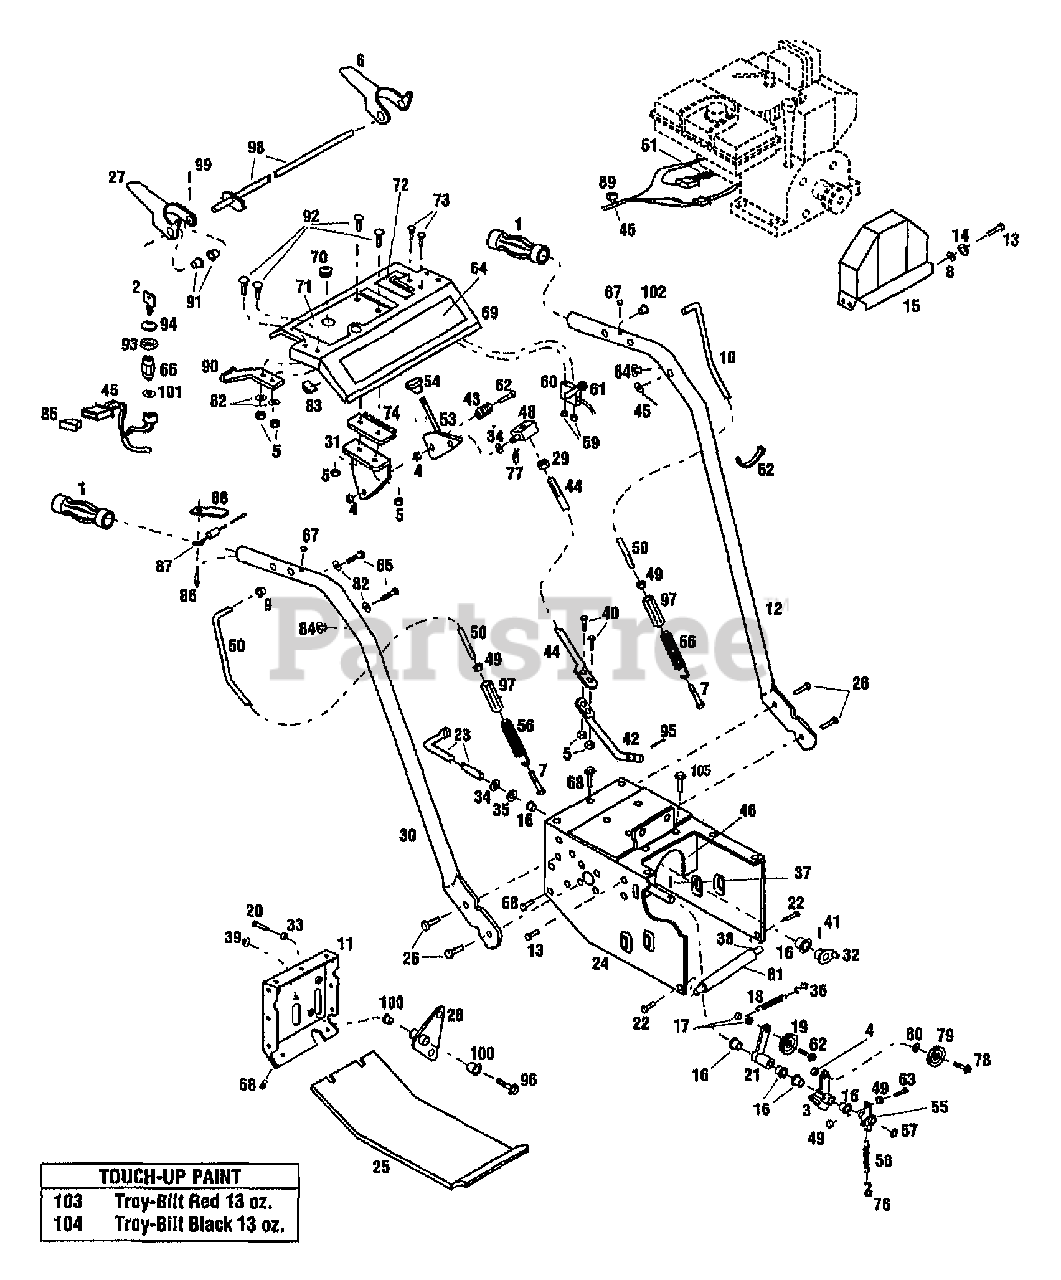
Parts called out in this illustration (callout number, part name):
1	GRIP-HANDLE
2	KEY-IGNITION
3	ARM-IDLER
4	NUT-LOCK 3/8-16
5	NUT-HT LK 1/4-20
6	HANDLE-CONTROL LH
7	SCR-PH 5/16-18X1.0
8	WASHER-FLAT 5/16 SAE
8	WASHER-LK .312 ZP
9	NUT-PUSH
10	ROD-CLUTCH WHEEL DRIVE
11	PLATE-BACK
12	HANDLEBAR-LH
13	SCR-HHC 5/16-18X.75 GR 5 ZP
14	WASHER-FLAT 5/16 SAE
15	COVER-BELT
16	BUSHING-.5X.21 NYLON FLNG
17	NUT-HEX/JAM 3/8-16 ZP
18	SPRING-EXTENSION
19	PULLEY-IDLER
20	SCR-HFLK 5/16-18X1.75 ZP G5
21	ARM-IDLER
22	SCR-HFLK 5/16-18X.75 ZP
23	ARM-CONTROL
24	ASSM-FRAME
25	COVER-BOTTOM
27	HANDLE-CONTROL RH
28	ARM-CONTROL SPEED
29	NUT-HEX 3/8-16 ZP
30	HANDLEBAR-RH
31	BRKT-CONTROL
32	ARM-CONTROL
33	NUT-HEX JAM 5/16-18
34	WASHER-FLAT .88X.5X.06 ZP
35	WASHER-BOW .74X.52X.01
36	HOOK-J
37	PIN-COTTER .093X1.00 ZP
38	BRACE-CROSS
39	NUT-HFLK 3/8-16 ZP
40	SCR-HH 1/4-20X.75 G5 ZP
41	PIN-ROLL .125X.75 ZP
42	ROD-CONTROL LOWER
43	SPRING-COMPRESSION
44	ROD-CONTROL UPPER
45	HARNESS-WIRING
46	ASSM-SUPPORT ZP
48	BLOCK-SWIVEL
49	NUT-HEX 1/4-20 ZP
50	ROD-CONTROL AUGER
51	CONNECTOR
52	TIE-CABLE NYLON BLACK
53	ARM-CONTROL SHIFT
55	ASSM-BRAKE ARM
56	SPRING-EXTENSION
57	WASHER-1.06X.531X.1 ZP
58	SPRING-EXTENSION
59	NUT W/LKWASHER 10-24 ZP
60	CONTROL-THROTTLE
61	KNOB
62	SCR-HH 3/8-16X1.75 G5 ZP
63	SCR-HH 1/4-20X1.0
64	DECAL-LOGO 42010
64	DECAL-LOGO 42012
65	SCR-FLANGE 1/4-20X3/4 GR5
66	SWITCH-IGNITION
67	BUMPER-RUBBER
68	SCR-HFLK 5/16-18X.75
69	CONSOLE-H/BAR W/DECALS
69	ASSM-CONSOLE
70	GROMMET-FLIP
71	DECAL-OPERATING INST
72	DECAL-THROTTLE
72	DECAL-WHEEL DRIVE
73	SCR-TRUSS #10-24 X 5/8
74	QUADRANT-SHIFT
77	CLIP-HAIRPIN .07 DIA
78	SCR-HH 3/8-16X1.5 G5 ZP
78	SCR-HH 3/8-16X2.0 G5 ZP
79	PULLEY-IDLER
79	IDLER-FLAT
80	WASHER-.875X.390X.134
81	TUBE-PLASTIC
82	WASHER-FLAT 1/4 SAE
83	CLIP-CORD
84	BUSHING
85	CONNECTOR
86	RIVET-POP .125
87	ASSM-RESISTOR
88	CLAMP
89	FUSE, 7.5 AMP
90	SPRING-FLAT
91	BEARING-FLANGE
92	SCR-RH 1/4-20X.675
93	NUT-SWITCH
94	CAP-SWITCH
95	PIN-COTTER .09X.75 ZP
96	SCR-SHLDR 3/8-16
97	NUT-ADJ
98	ROD-CONTROL HANDLE
99	PIN-ROLL .125 X .62
100	BUSHING-.5X.5 NYLON FLNG
101	WASHER-LK .625 INT TOOTH
102	BUSHING-NYLON
103	PAINT-RED SPRAYCAN POWDER
104	PAINT-BLACK SPRAY
105	SCR-HFLK 5/16-18X.50 ZP
